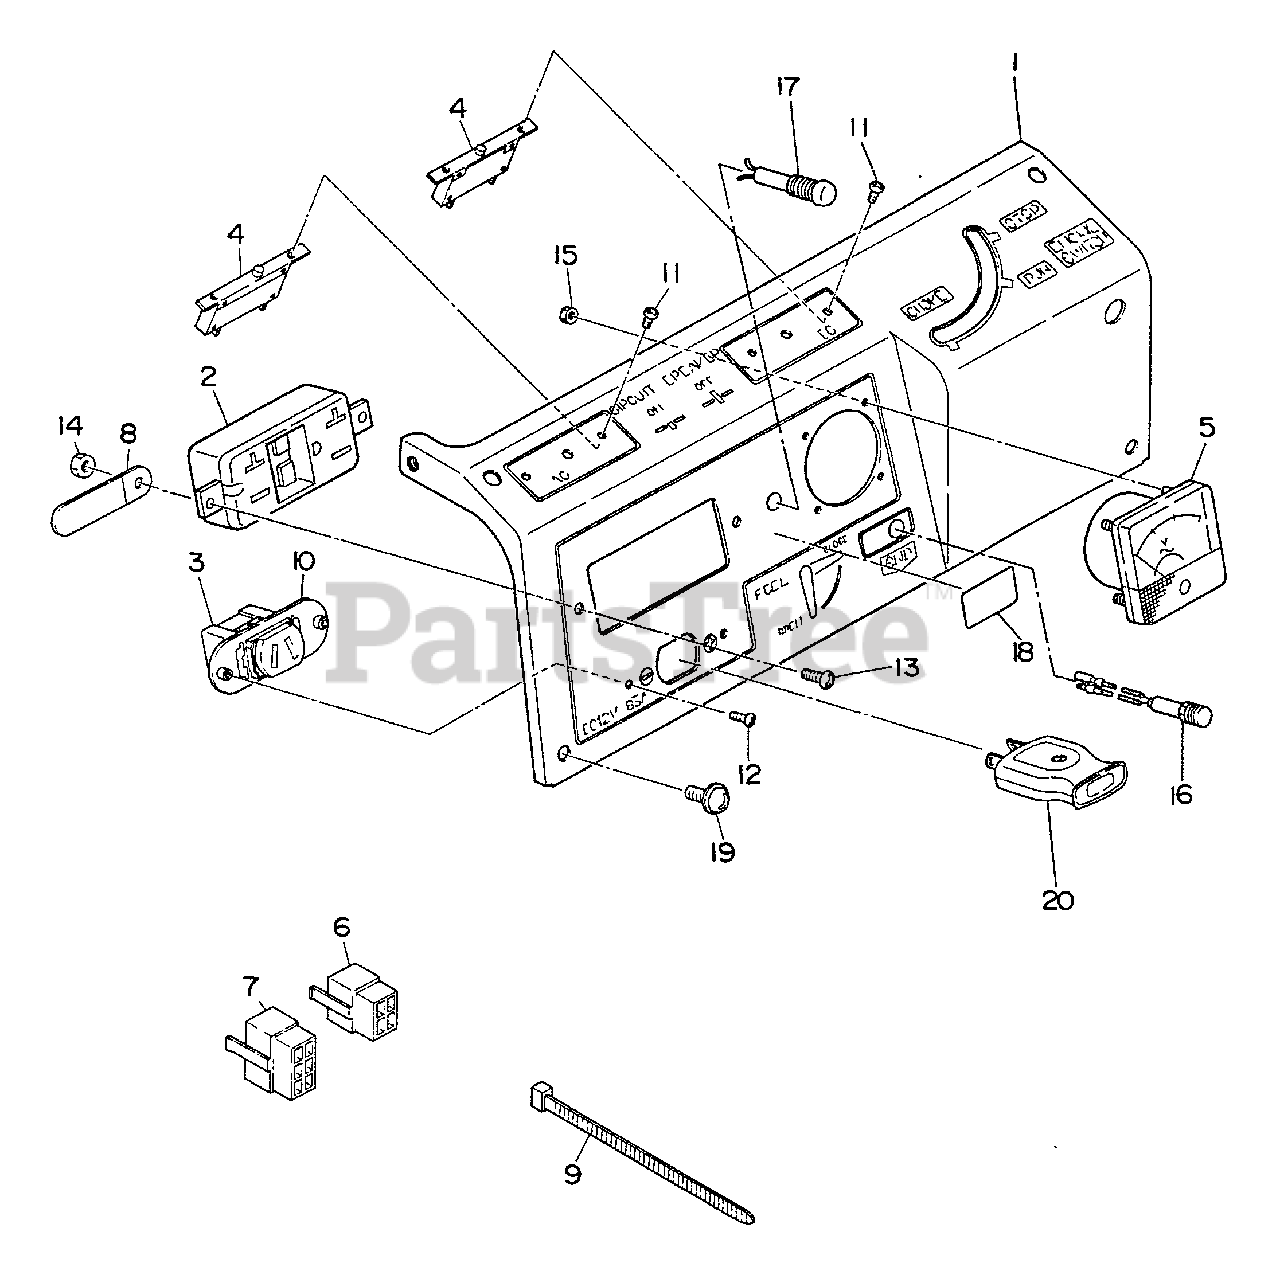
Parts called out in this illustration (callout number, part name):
1	CONTROL PANEL ASSY
2	AC RECEPTACLE - 125V-20A, GFCI
3	DC RECEPTACLE -- 250V-10A
4	CIRCUIT BREAKER - 10A DC
5	AC VOLT METER
6	CONNECTOR
7	CONNECTOR
8	CLAMP
9	TIE, CABLE
10	DC RECEPTACLE BASE
11	SCREW
12	SCREW
13	SCREW
14	NUT
15	NUT
16	LED LAMP ASS'Y
17	LAMP, NEON
18	LABEL -- HZ-V
19	SCREW
